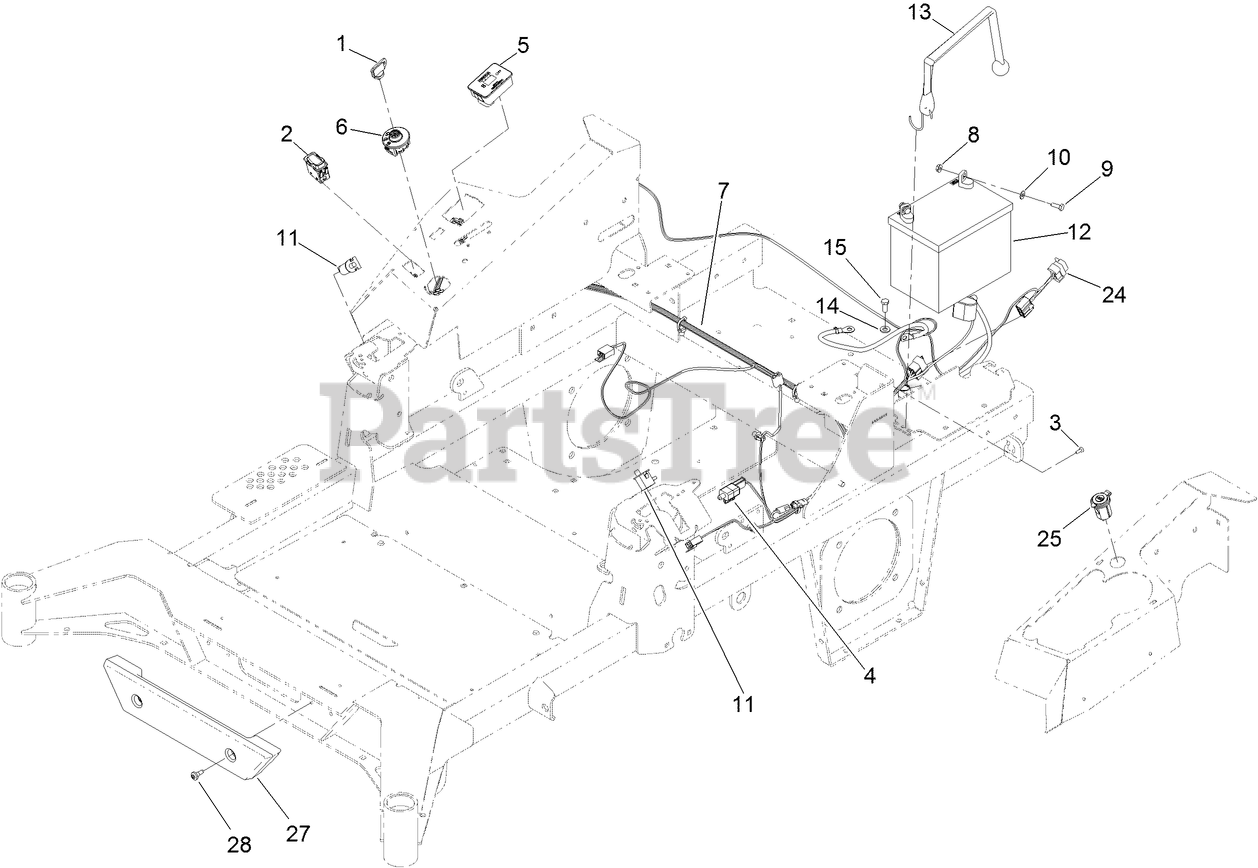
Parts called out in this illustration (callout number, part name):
1	KEYS-IGNITION (SPARE PAIR)
1	KEY-IGNITION
2	SWITCH-ROCKER, ON-NONE-ON
3	SCREW-FORMING, THREAD
4	SWITCH
5	MODULE ASM
6	SWITCH-IGNITION
7	HARNESS-WIRE
8	NUT-HF
9	SCREW-HH
10	WASHER-FLAT
11	SWITCH-BAIL
12	BATTERY-DRY
13	STRAP-BUNGEE
14	WASHER-PLAIN
15	SCREW-HH
24	HARNESS-WIRE, ADAPTER
25	PORT-POWER, USB
27	BUMPER-FRONT
28	SCREW-SHOULDER
